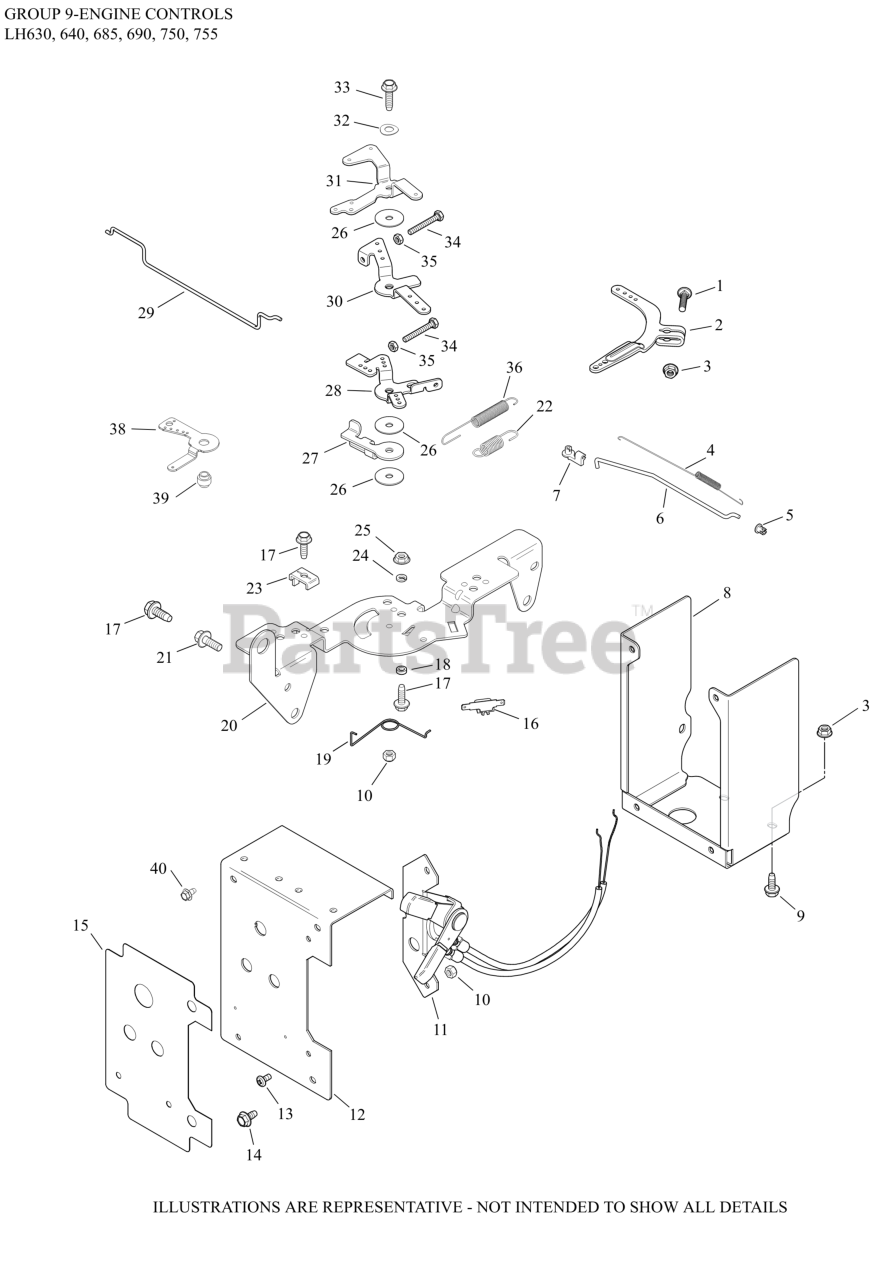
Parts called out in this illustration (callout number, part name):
1	BOLT, RD HD SQ NECK M6X1.0X25
2	LEVER, GOVERNOR - (#2409069S)
3	NUT, FLG M6X1.0
4	SPRING, LINKAGE
5	BUSHING, LINKAGE RETAINING
6	LINKAGE, THROTTLE
7	BUSHING, THROTTLE LINKAGE
9	SCREW, THREAD FORMING
10	NUT, LOCK M5X.8
17	SCREW, THREAD FORMING
19	SPRING, CHOKE RETURN
20	BRACKET, CONTROL
22	SPRING, GOVERNOR (BLACK)
23	CLAMP, CABLE-(#2523753S)
24	WASHER, SPRING LOCK 1/4"
25	NUT, FLG M5X.8
26	WASHER, FLAT 5.5 MM
27	LEVER, THROTTLE ACTUATOR
28	LEVER, THROTTLE CONTROL
29	LINKAGE, CHOKE
31	LEVER, CHOKE
32	WASHER, SPRING 1/4"
33	SCREW, THD FRM-USE 25 086 473-S
34	SCREW, CAP M4X.7X30
35	NUT, M4X0.7
36	SPRING, THROTTLE LIMITER
37	LEVER, GOVERNOR ASSEMBLY
